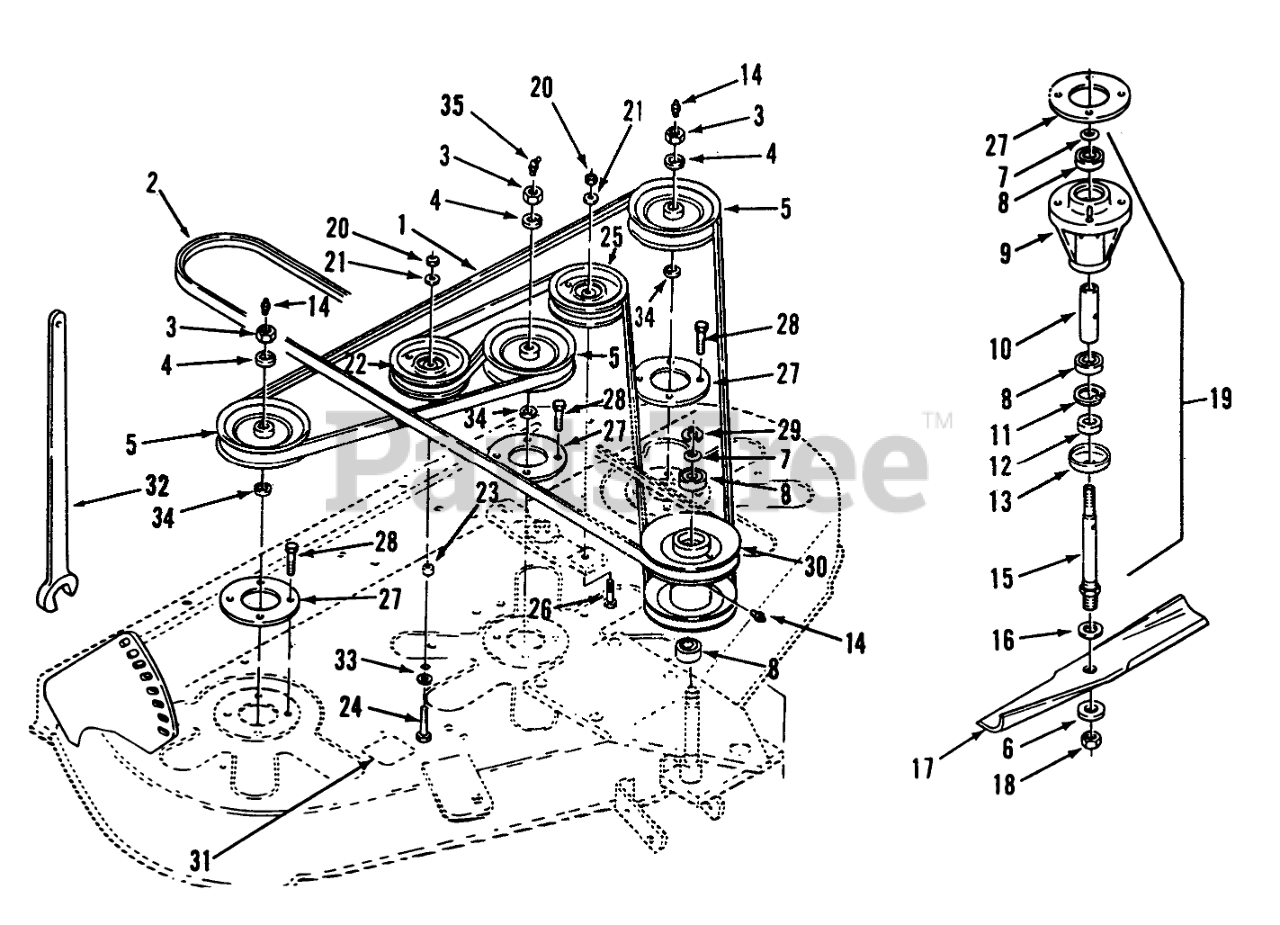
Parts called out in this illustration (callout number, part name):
1	V-BELT
2	V-BELT
3	NUT-JAM
4	WASHER-LOCK
5	PULLEY-SPINDLE
6	WASHER-FLAT
7	O RING
8	BEARING-BALL
9	HOUSING-SPINDLE
11	RING-RETAINING
12	SPACER-BLADE
13	CUP-SPINDLE
14	FITTING-GREASE
15	SHAFT-SPINDLE
16	Washer
17	SERV ASS'Y-BLADE PKG
18	NUT-JAM
19	Spindle Assembly
20	NUT-LOCK, NI
21	WASHER-FLAT
22	Pulley-Idler
23	SPACER
24	SCREW-HH
25	PULLEY-FLAT IDLER
26	BOLT
27	SPACER-SPINDLE
28	SCREW-HH
29	RETAINING RING
30	PULLEY-COUNTER SHAFT
31	DECAL-BELT INSTALL
32	Spindle Wrench
33	WASHER
34	WASHER-FLAT
35	FITTING-GREASE
